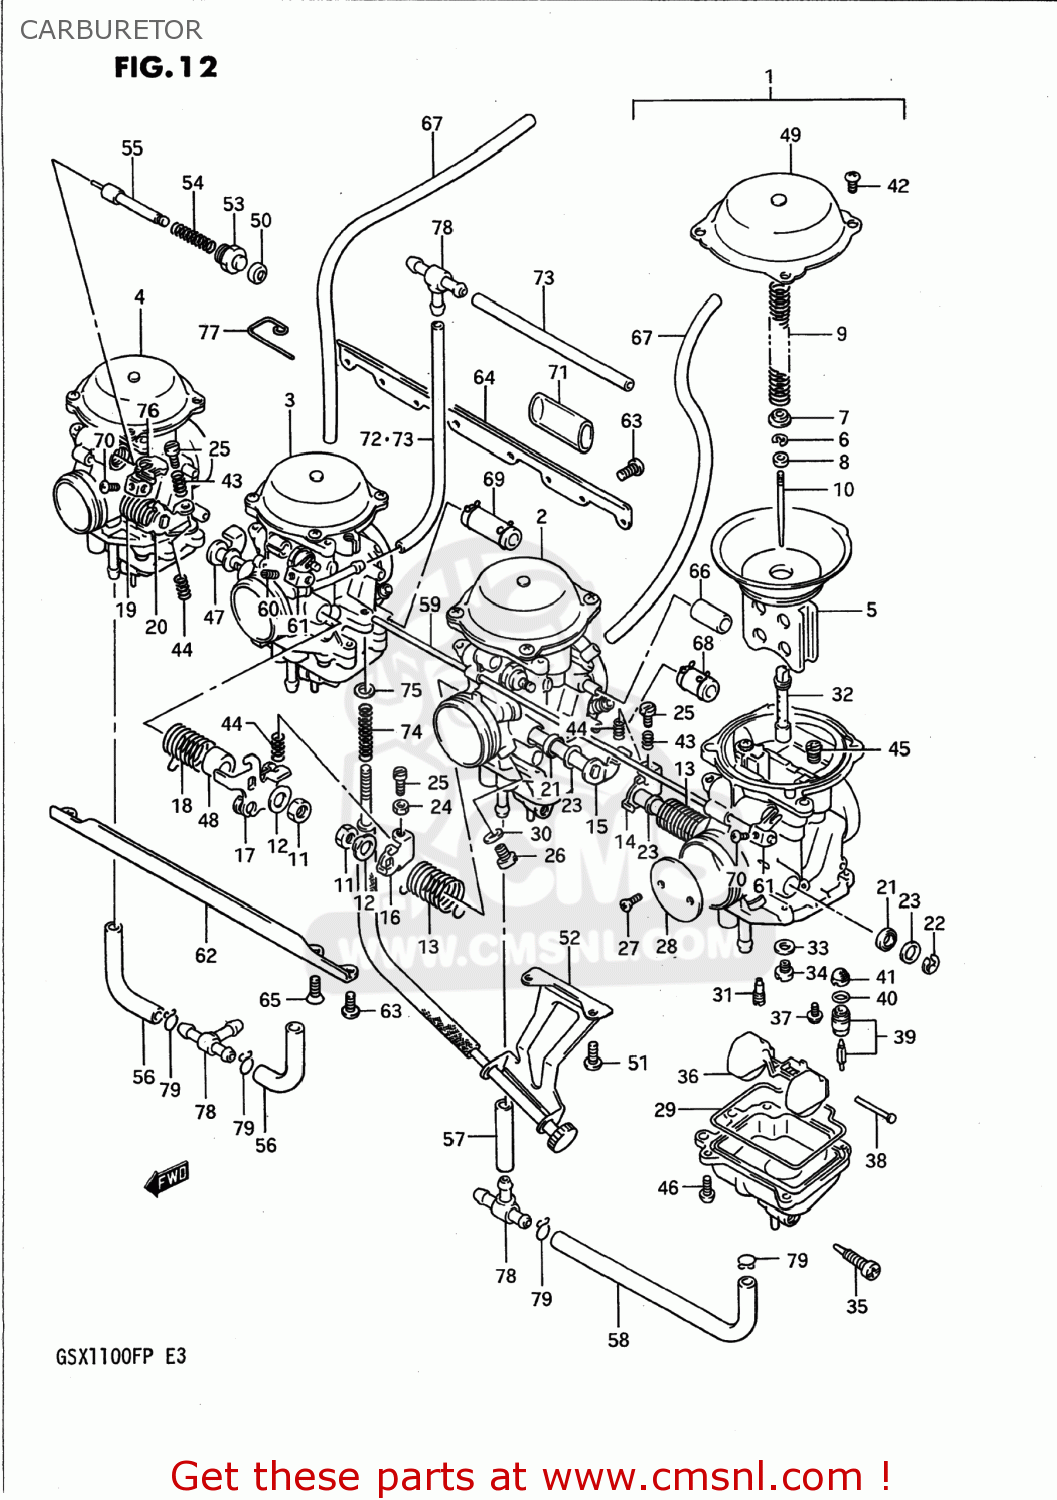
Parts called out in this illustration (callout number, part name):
1	CARBURETOR ASSEMBLY,LEFT
2	CARBURETOR ASSEMBLY
3	(CA) CARBURETOR ASSEMBLY,MIDDLE
4	CARBURETOR ASSEMBLY,RIGHT
5	DIAPHRAGM ASSY
6	CLIP
7	RING
8	RING
9	SPRING
10	NEEDLE,JET
11	NUT
12	WASHER
13	SPRING
14	SHAFT ASSEMBLY
15	SHAFT ASSEMBLY
16	LEVER
17	LEVER ASSEMBLY
18	SPRING
19	SPRING
20	SHAFT ASSEMBLY
21	SEAL
22	E RING
23	GASKET,THROTTLE SHAFT (NAS)
24	NUT,THROTTLE ROD
25	SCREW
26	SCREW
27	SCREW
28	VALVE,THROTTLE (125)
29	O RING,FLOAT CHAMBER
30	WASHER
31	JET,PILOT(32.5)
32	JET,NEEDLE(P-0)
33	WASHER,NEEDLE NOZZLE
34	JET,MAIN(110)
35	SCREW
36	FLOAT
37	SCREW
38	PIN,FLOAT
39	VALVE ASSY,NEEDLE
40	O-RING,NEEDLE VALVE
41	FILTER
42	SCREW
43	SPRING
44	SPRING,THROTTLE SCREW
45	JET,AIR
46	SCREW
47	SHAFT ASSEMBLY
48	RING
49	COVER,DIAPHRAGM
50	CAP,STARTER VALVE
51	SCREW
52	BRACKET ASSY
53	GUIDE SCREW,PLUNGER
54	SPRING
55	PLUNGER ASSY
56	HOSE
57	HOSE
58	HOSE
59	SHAFT,STARTER
60	SCREW
61	LEVER
62	PLATE
63	SCREW
64	PLATE
65	SCREW(5X14)
66	HOSE,CARBURETOR
67	HOSE
68	HOSE SET (3X5X18)
69	HOSE ASSY
70	SCREW,THROTTLE ADJUST
71	HOSE(16X19X100)
72	HOSE
73	HOSE
74	SPRING
75	WASHER
76	LEVER
77	CLIP
78	NIPPLE
79	CLIP
